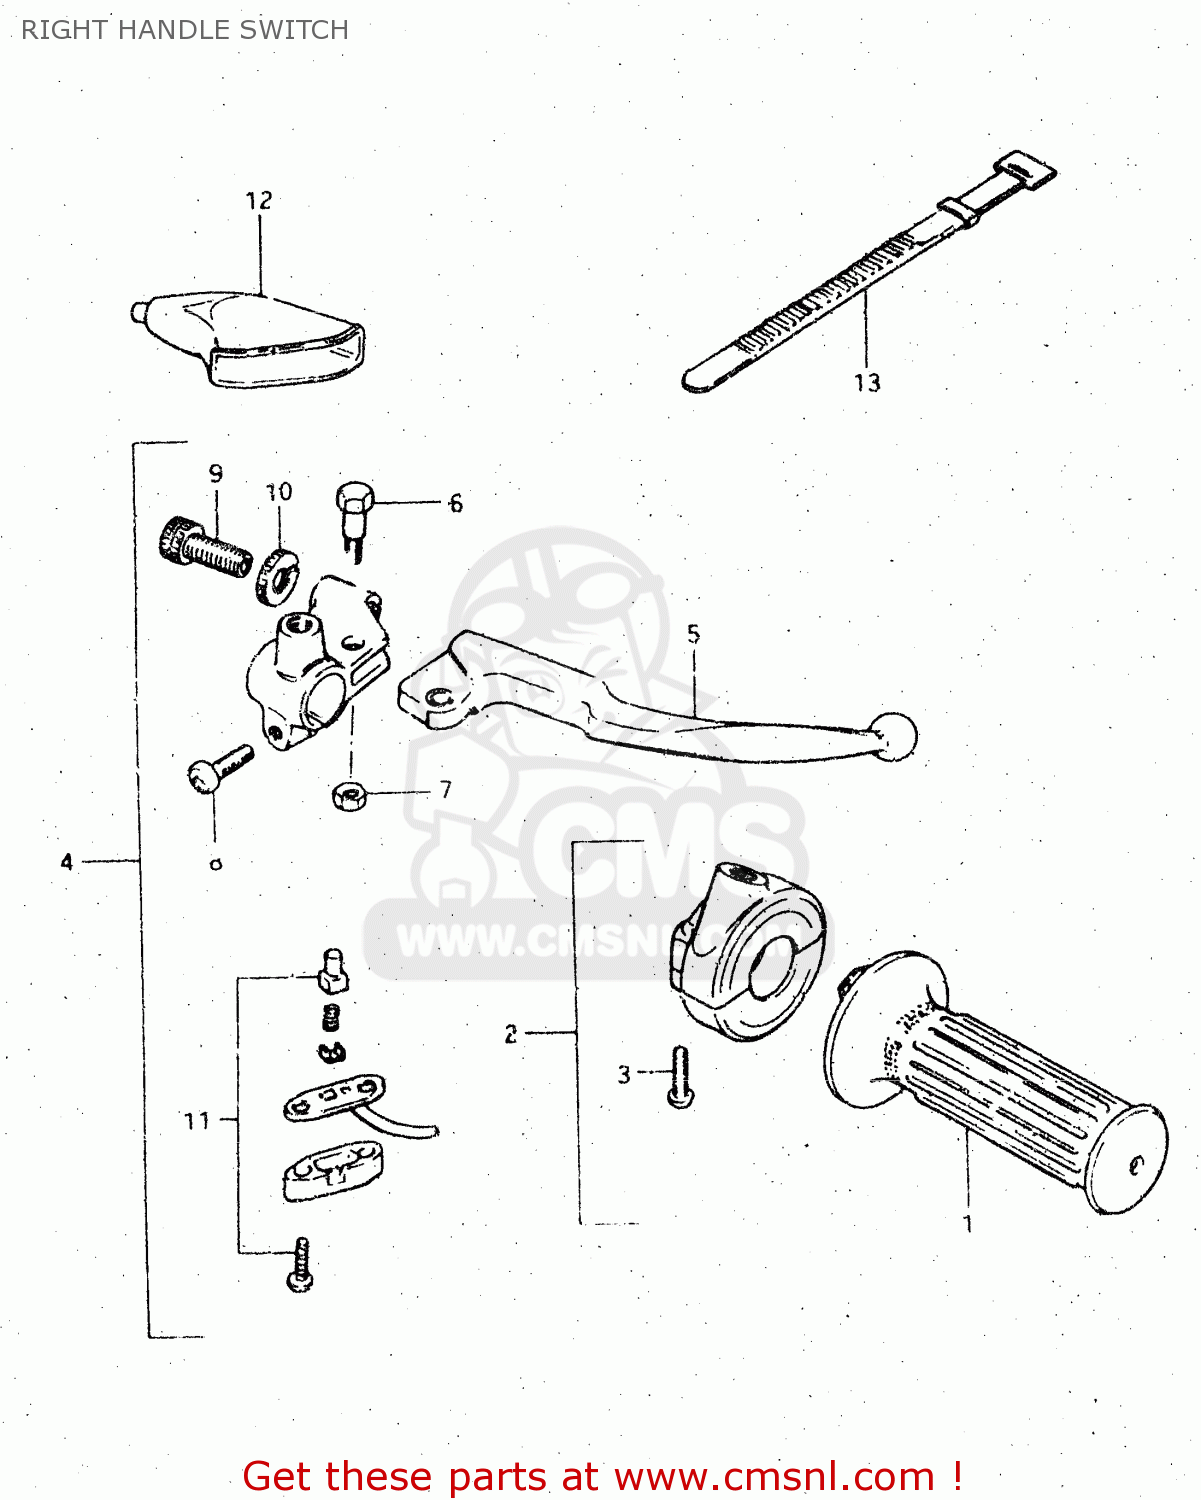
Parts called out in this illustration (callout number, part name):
1	GRIP,THROTTLE
2	CASE ASSY,THROTTLE
3	SCREW 5X20
4	LEVER ASSEMBLY,BRAKE
5	LEVER,BRAKE
6	BOLT,LEVER
7	NUT 6MM
8	SCREW
9	ADJUSTER,CABLE
10	NUT,CABLE ADJUSTER
11	SWITCH ASSEMBLY
12	DUST SEAL,BRAKE/CLUTCH
13	CLAMP
